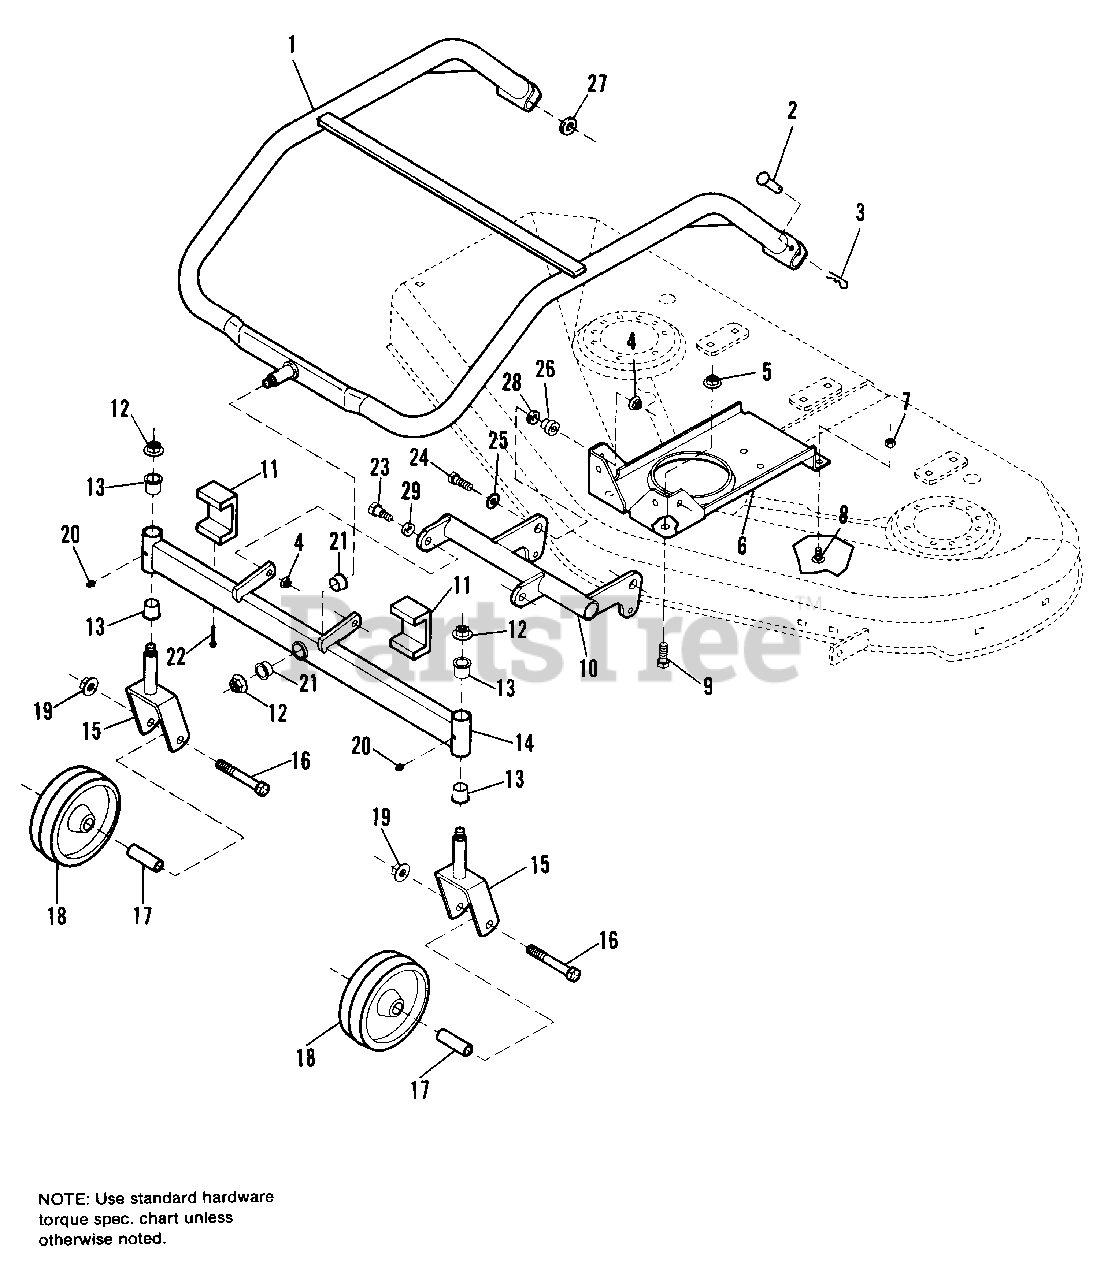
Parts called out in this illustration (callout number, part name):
1	MOWER ARM ASSY. (1691662)
1	MOWER ARM ASSY. (1691665)
2	PIN, Hitch
3	PIN, Hair Pin
4	NUT, Hex Whizlock, 3/8-16
5	NUT, Whizlock, 7/16-14
6	SUPPORT ASSY.
7	NUT, Hex Whizlock, 5/16-18
8	CARRIAGE BOLT, 5/16-18 x 3/4
9	CAPSCREW, Whizlock, 7/16-14 x 1
10	ROCKER ARM ASSY.
11	BEARING, Block
12	NUT, Centerlock, 1/2-13
14	AXLE ASSY., Mower (Incl. Ref. Nos. 11 & 22)
16	CAPSCREW, Hex, 1/2-13 x 3-1/2
19	NUT, Esna Lock, 1/2-13 (Thin)
20	FITTING, Grease, 1/4
22	SCREW, Self-Tapping
23	BOLT, Shoulder, 3/8-16 X 1.34
24	CAPSCREW, Hex, 3/8-16 x 1-1/2
25	WASHER, 3/8
27	WASHER, 5/8
28	WASHER, Plain
29	WASHER, Plain
